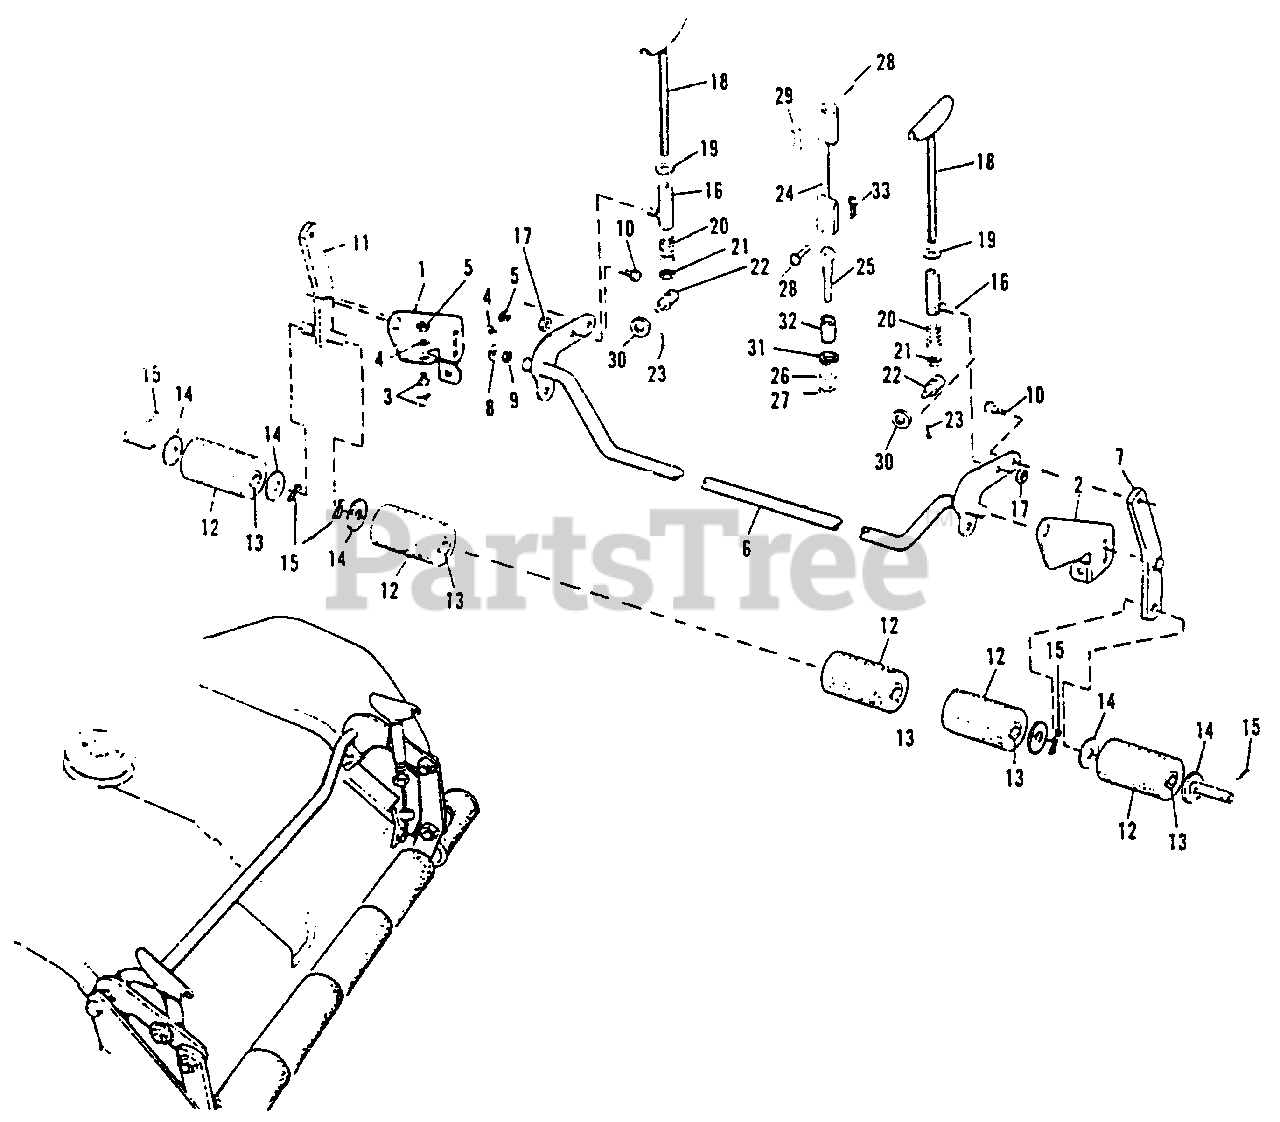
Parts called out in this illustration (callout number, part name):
1	R.H. Roller Bracket
2	L.H. Roller Bracket
3	Carriage Bolt, 3/8"-16 x 3/4"
4	Lock Washer 3/8"
5	Full Hex. Nut, 3/8"-16
6	Rocker Assembly Arm
7	Roller Bar Assembly L.H.
8	Plain Washer, 3/8"
9	Full Hex. Nut, 3/8"-16
10	Hex. Cap Screw, 3/8"-16 x 1"
11	Roller Shaft Assembly
12	Roller W/Bushing
15	Cotter Pin, 3/16"-1"
16	Socket Crank Assembly
17	Full Hex. Nut. 3/16"-16
18	Adjusting Screw Assembly
19	Plain Washer 3/8"
20	Adjusting Screw Spring
21	Hex. Jam Nut, 3/8"-16
23	Cotter Pin, 3/32" x 3/4"
24	Cable Assembly, Lift
26	Washer, Lock, 3/8" Std.
27	Nut, Hex., Full, 3/8"-16 NC
29	Clip, Spring
30	Plain Washer, 5/16"
31	Plain Flat Washer 3/8"
33	Cotter Pin. 3/32" x 3/4"
